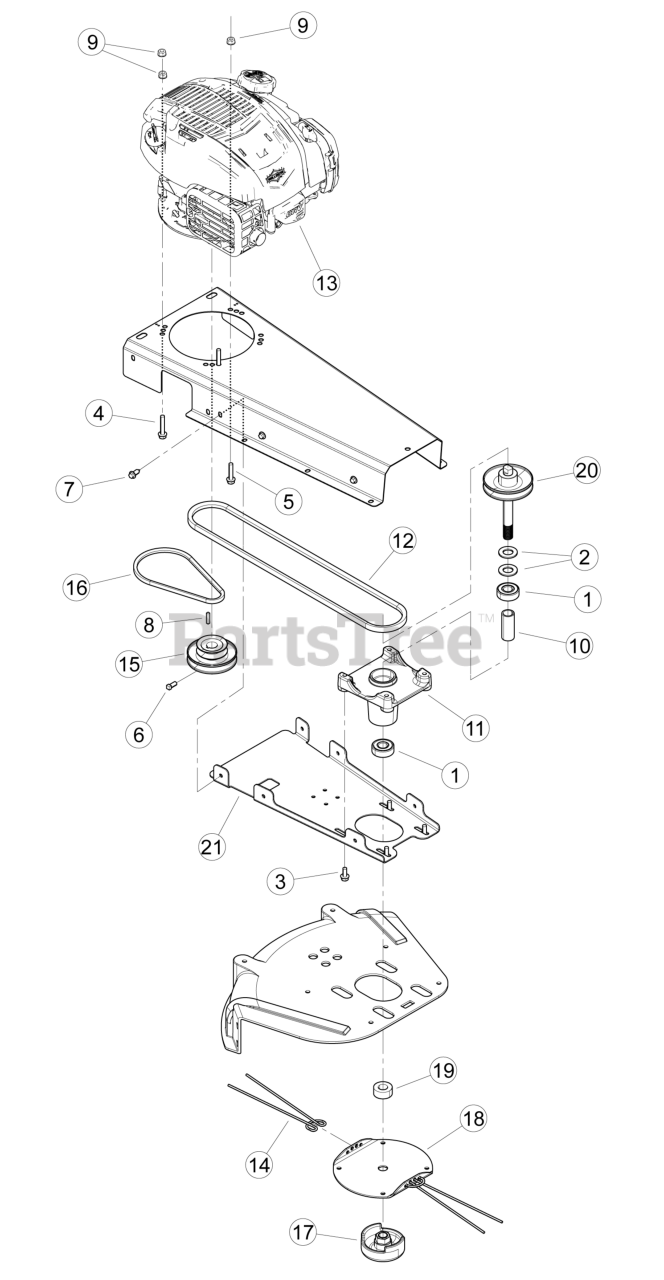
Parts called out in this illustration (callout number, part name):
1	BEARING, 3/4 BALL
2	WASHER, 3/4" SAE FLAT ZP
3	BOLT, 5/16 × 3/4 FLANGE NC
4	BOLT, 5/16 × 1-1/2 FLANGE NC
5	BOLT, 5/16 × 1-1/4 FLANGE NC
6	SCREW, 5/16-18 × 5/8 SQ HD SET
7	SCREW, 11/32-12 × 7/8 FLANGE T-AB
8	KEY, 3/16 SQ X 1.75
9	NUT, 5/16-18 NYLOCK FLANGE
10	SPACER, TRIMMER SPINDLE
11	CASTING, TRIMMER SPINDLE HUB
12	BELT, AX48
13	ENGINE, BRIGGS 163cc VERTICAL
14	STRING, 20" X .155 DIA. CROSS-FIRE
15	PULLEY, 4.0/2.5 X .875
16	BELT, 3L220
17	MOWBALL, CAST TRIMMER PAINTED
18	DISK, TRIMMER HEAD
19	SPACER, TRIMMER HEAD
20	WELDMENT, SPINDLE HW MODELS
21	PLATE, HWS SPINDLE CASTING MOUNT
